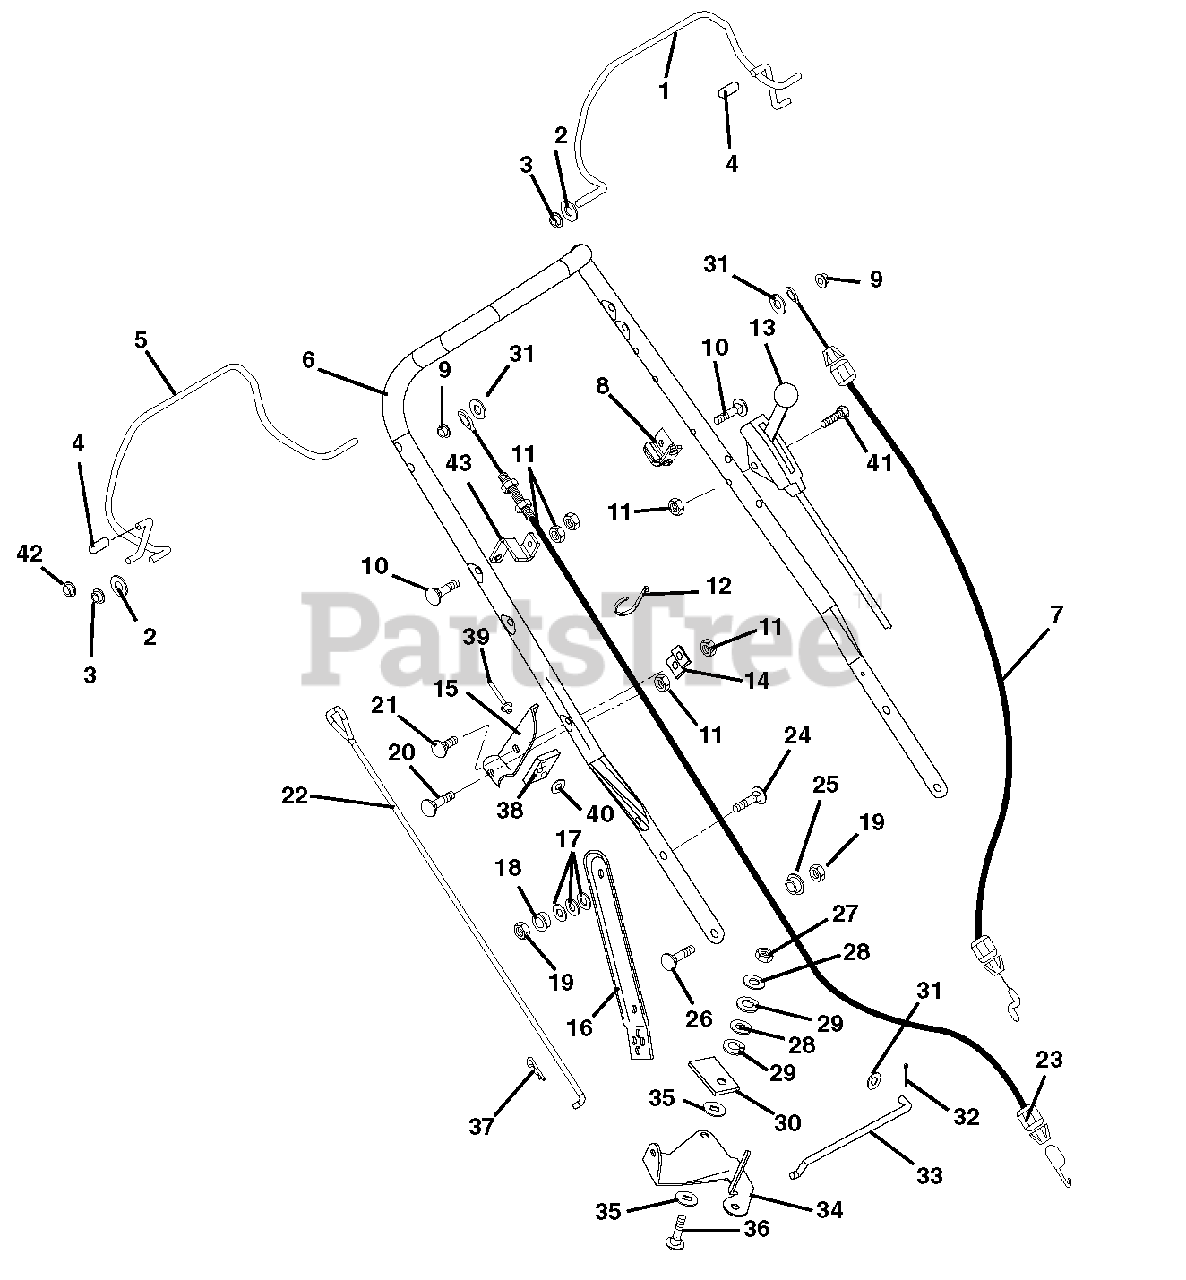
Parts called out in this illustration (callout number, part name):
1	Bail, Engine
2	Washer, Flat Steel .32 x .44 x .44 x .56 (911183, 184)
3	Bushing, Flange .325 x .688 x .560 (911183, 184)
4	Cap, Vinyl .25 I.D. (911183, 184)
5	Traction Bail (911183, 184)
6	Handlebar
7	Cable, OPC (911160)
8	Cable, Anchor
9	Push Nut, .25
10	Bolt, Round Head Square Neck .25-20 x 1.25 (911183, 184)
11	Nut, Locking Center .25-20 (911183, 184)
12	Cable Tie
13	Cable, Lockout Control (911184)
14	Brace, Speed Control (911183, 184)
15	Bracket, Speed Control (911183, 184)
16	Link, Handlebar Adjuster Left Hand
17	Washer, Bellville Spring
18	Bushing, Flange .325 x .50 x .513 x .875
19	Nut, Locking Center .31-18
20	Bolt, Round Head Square Neck .25-20 x 1.38
21	Bolt, Round Head Square Neck .25-20 x .50 Grade
22	Rod, Speed Control (911183, 184)
23	Traction Cable (911183, 184)
24	Bolt, Round Head Square Neck .31-18 x 1.00 Grade 5
25	Shoulder Spacer
26	Bolt, Round Head Square Neck .31-18 x .75 Grade 5
27	Nut, Locking Center .38-16 (911183, 184)
28	Washer, Flat Steel .406 x .812 x .065 (911183, 184)
29	Washer, Lock .375 x .115 Heavy (911183, 184)
30	Pressure Flange (911183, 184)
31	Washer, Flat Steel .281 x .62 x .065 (911183, 184)
32	Pin, Cotter .06 x .50 (911183, 184)
33	Shift Link (911183, 184)
34	Bell Crank, Speed Control (911183, 184)
35	Friction Washer (911183, 184)
36	Bolt, Round Head Square Neck .38-16 x 1.25 (911183, 184)
37	Pin, Hair Internal .08 x .18 x 1.18 (911183, 184)
38	Support Pad
39	Rivet .187 x .575
40	Washer, Flat Steel .219 x .50 x .049
41	Bolt, Round Head Square Neck .25-20 x 2.00 Grade 5 (911184)
42	Nut, Push .312
43	Anchor, Cable (911183, 184)
